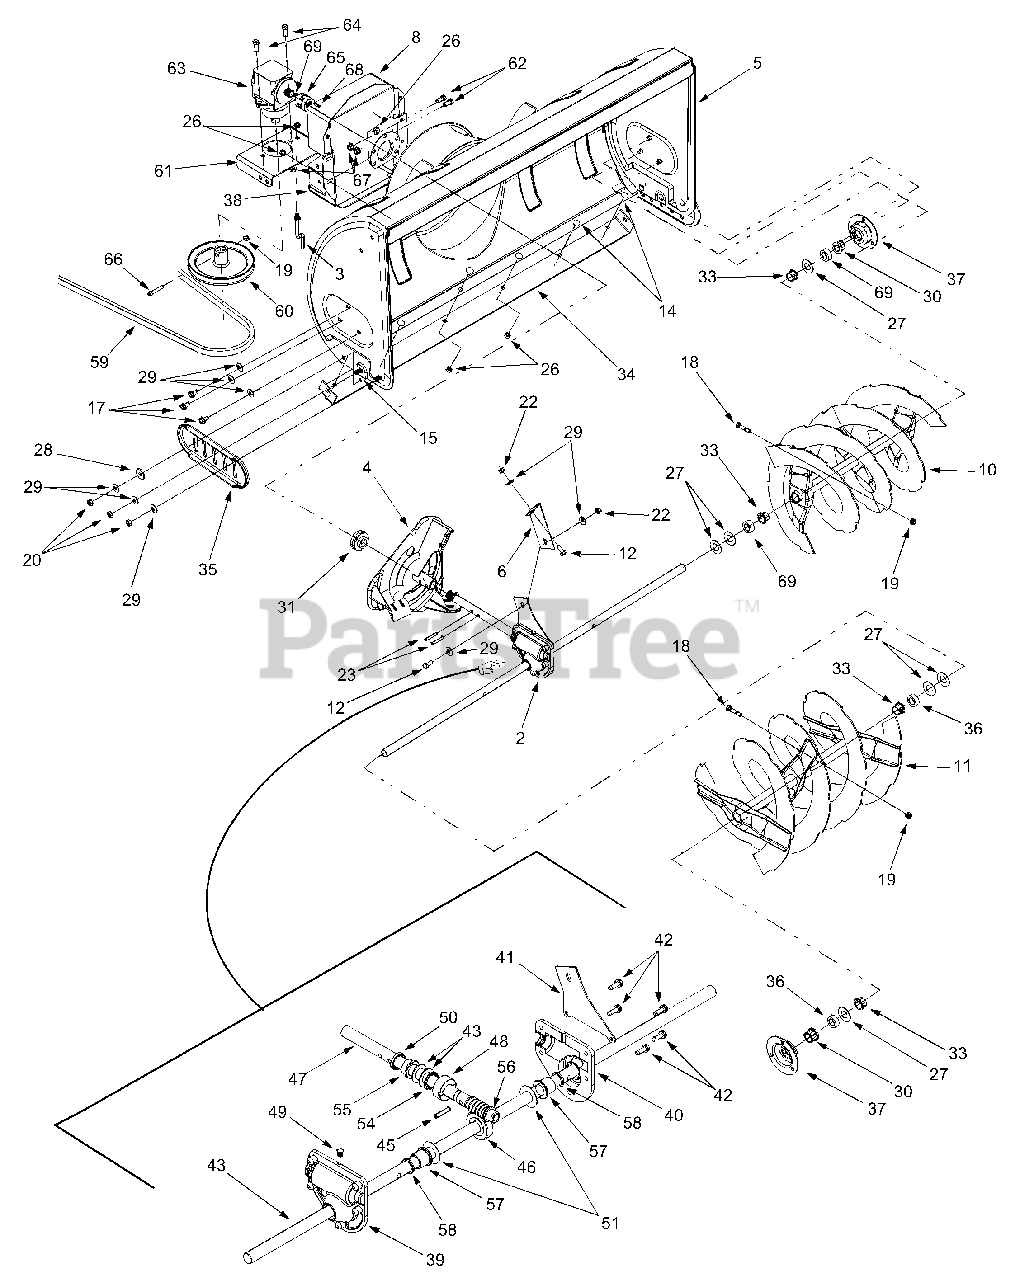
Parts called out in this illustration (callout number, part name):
1	Bearing Housing, 1.85 ID
2	Auger Gear Case
3	Belt Keeper Rod
4	Impeller Assembly, 12"
10	LH Spiral Auger, 40"
11	RH Spiral Auger, 40"
12	Hex Cap Screw, 5/16-24 x .75
13	Carriage Screw, 1/4-20 x .5
14	Carriage Bolt, 5/16-18 x .62
15	Splined Carriage Screw, 5/16-18 x 1.0
16	Carriage Bolt, 5/16-18 x .75
17	Self Tapping Screw, 5/16-18 x .625
18	Shear Bolt, 5/16-18 x 1.5
19	Hex Lock Nut, 5/16-18
20	Hex Nut, 5/16-18
21	Hex Flange Lock Nut, 1/4-20
22	Hex Nut, 5/16-24
23	Spirol Pin, 1/4 x 1-1/2
24	Spirol Pin, .125 x .812
25	Adapter Chute
26	Flange Lock Nut, 5/16-18
27	Flat Washer, .76 x 1.49 x .06
28	Flat Washer, .344 x 1.125 x .12
29	Bell Washer, .340 x .872
30	Hex Flange Bearing, .75 ID
31	Flange Ball Bearing, .75 x 1.85
32	Plastic Bushing, .38
33	Flange Bushing, .80 x .91
34	Skid Plate Bracket, 42"
35	Slide Shoe
36	Spacer, .75 x .125 x .5
37	Hex Bearing Housing, 1.0
38	Skid Plate
39	RH Reducer Housing
40	LH Reducer Housing
42	Self Tapping Screw, 1/4-20 x .75
43	Spiral Axle, 41.5"
44	Hi-Pro Key, 3/16 x 5/8
45	Spring Spirol Pin, .25 x 1.25
46	Worm Gear, 20-tooth
47	Worm Shaft
48	Thrust Collar
49	Grease Plug
50	Grease Seal
51	Flat Washer, .76 x 1.5 x .030
52	Flat Washer, .508 x 1.0 x .020
53	Thrust Washer, .75 x 1.25 x .0615
54	Thrust Bearing, .75 x 1.25 x .078
55	Flange Bearing, .75 x 1.0 x .59
56	Flange Bearing, .503 x .75
57	Flange Bearing, .754 x 1.0 x .925
58	Grease Seal
59	Lower V-belt
60	Drive Pulley, 7"
61	Drive Mounting Bracket
62	Hex Cap Screw, 3/8-16 x .75
63	Right Angle Drive
64	Hex Cap Screw, 3/8-16 x 1.0
65	Coupling
66	Socket Head Cap Screw, 5/16-18 x
67	Flange Lock Nut, 3/8-16
68	Square Key, 3/16 x .75
69	Hi-pro Key, 3/16 x .75
70	Bearing Housing, 1.85 ID
